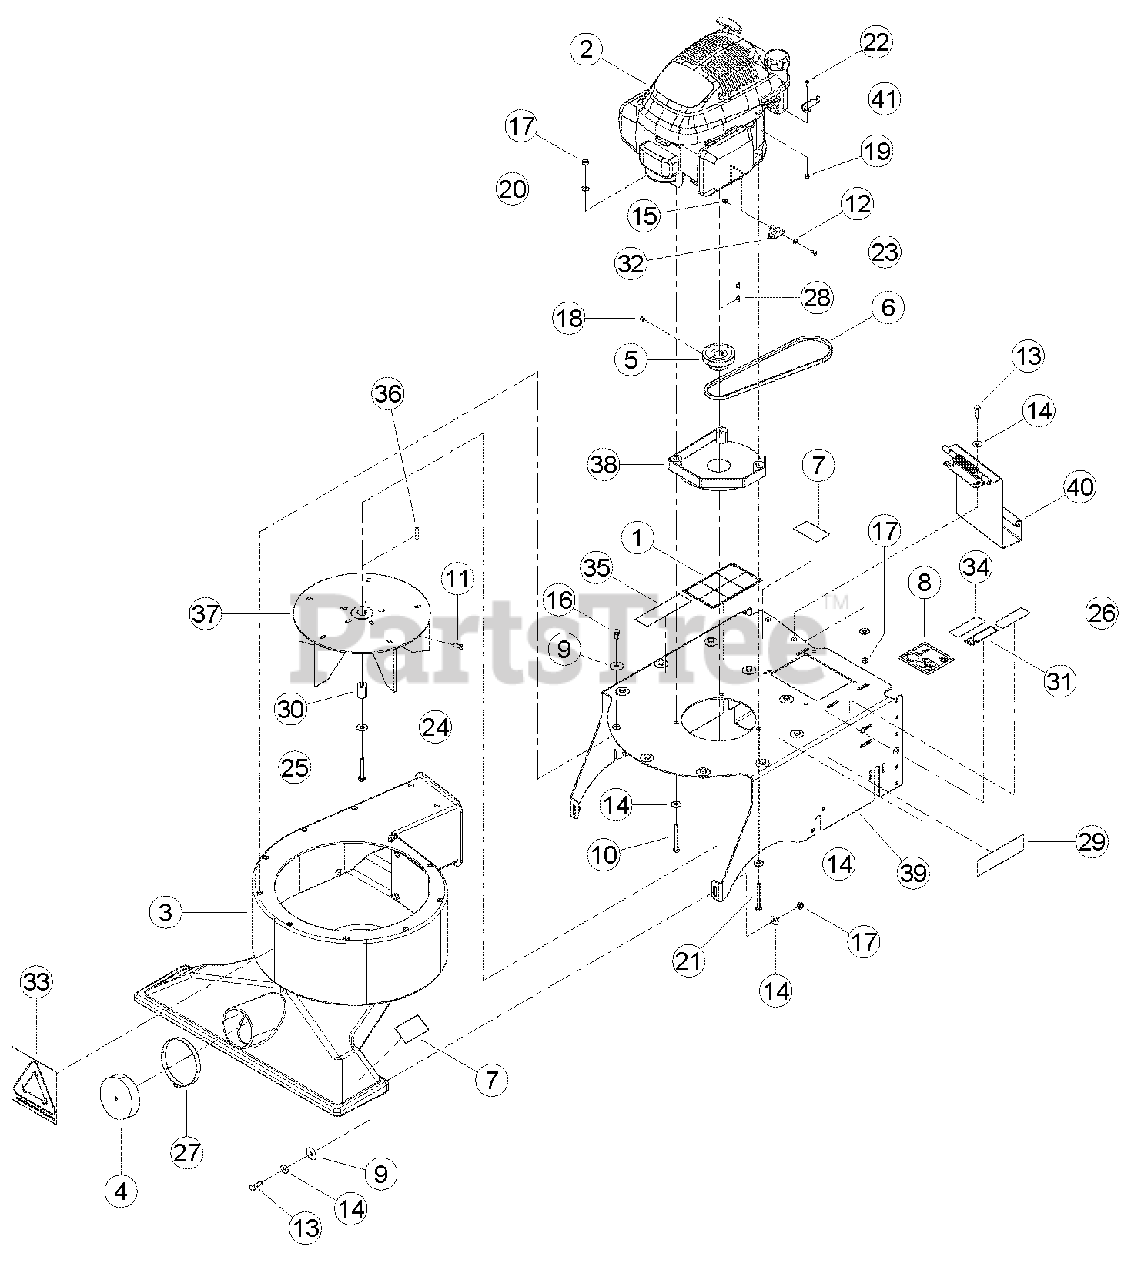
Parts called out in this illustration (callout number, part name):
1	DECAL, PROTECTION
2	ENGINE, 190CC B&S INTEK/IC VERTICAL (FOR SERVICE SEE ENGINE OWNER'S MANUAL OR YOUR NEAREST AUTHORIZED B&S ENGINE DEALER)
3	ASSY, FAN HOUSING W/INTAKE
4	CAP, ROUND VINYL (4 X 1)
5	PULLEY, 2.85 O.D. X 7/8 IN BORE
6	BELT, SP BEARVAC (3L32)
7	DECAL, DANGER
8	DECAL, 98 DB
9	WASHER, 5/16 FENDER
10	BOLT, 5/16 X 2-3/4 HCPS GR5
11	SCREW, 5/16-18 X 5/8 SQ HD SET
12	WASHER, #8 SAE FLAT
13	BOLT, 5/16 X 1 HEX HD
14	WASHER, 5/16 FLAT
15	NUT, #8 X 32 NYLOCK
16	BOLT, 5/16 X 5/8 HEX HD
17	NUT, 5/16 NYLOCK
18	SCREW, 5/16 X 3/8 SET
19	NUT, 10/24 NYLOCK TYPE NM ZP
20	WASHER, 5/16 SAE FLAT
21	BOLT, 5/16 X 4 HHCS GR5 ZP
22	SCREW, MCH 10-24 X 1/2 PAN HD PH ZP
23	SCREW, #8 X 32 X 3/4 PAN PHP ZP
24	WASHER, 3/8 GR8 USS ZP
25	BOLT, 3/8 NC X 2-1/4 HHCS NF GR8 ZP
26	DECAL, SERIAL NUMBER
27	CLAMP, 4 IN HOSE
28	KEY, 3/16 X 5/32 4 MM WDRFF JUMP
29	DECAL, ECHO BEARCAT 6.82 X 1.90
30	SPACER, .88 X 1.25
31	DECAL, 6 HP SP BEARVAC INFORMATION
32	SWITCH, HONDA ENGINE KILL
33	DECAL, COLLECT IT
34	DECAL, ATLANTIC BRIDGE LTD INFO
35	DECAL, MODEL WV190S
36	KEY, 3/16 X 1-1/4 SQUARE
37	WELDMENT, BEARVAC ROTOR
38	WELDMENT, BEARVAC ENGINE SUPPORT
39	SUPPORT, BEARVAC FRAME
40	ASSEMBLY, EXHAUST DOOR
41	PLATE, HONDA BRACKET HOLDER
